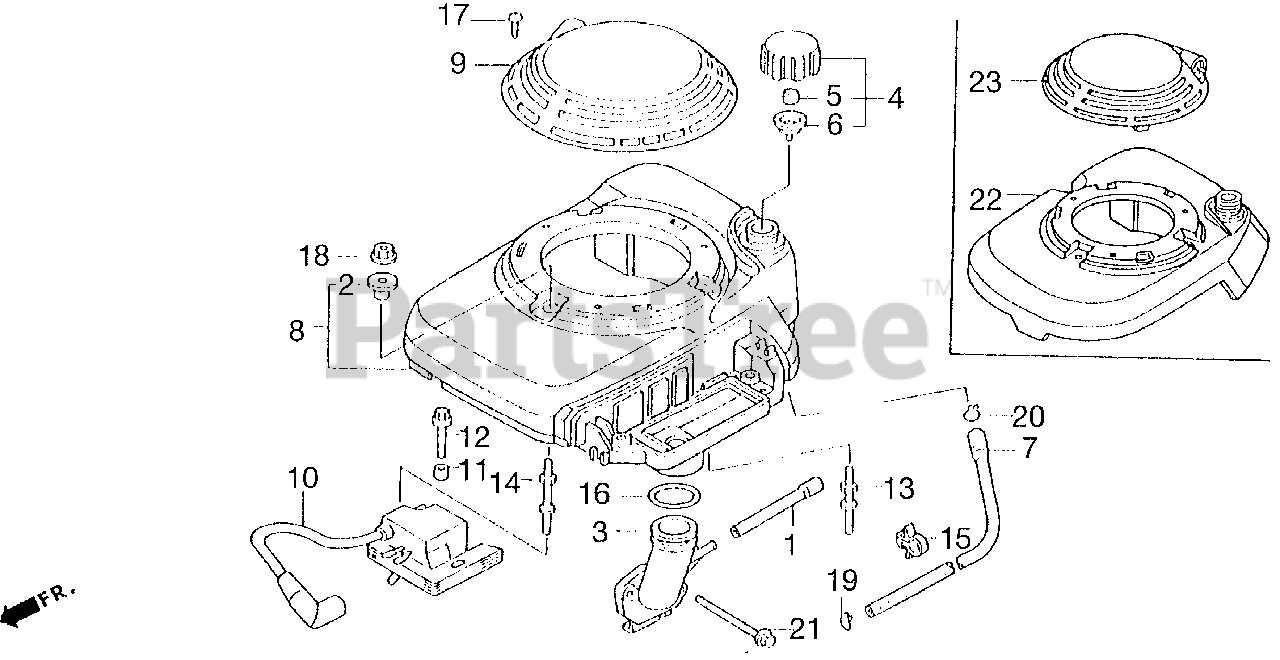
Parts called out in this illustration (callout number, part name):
1	TUBE, BREATHER
2	COLLAR, AIR CLEANER
3	ELBOW, AIR CLEANER
4	CAP ASSY., FUEL TANK
5	SPONGE, FUEL CAP BREATHER
6	GASKET, FUEL CAP
7	TUBE, FUEL TANK
8	COVER, FAN *R8* (TEXTURED) (BRIGHT RED)
8	COVER, FAN *R8* (BRIGHT RED)
9	HOOD, FAN COVER *R8* (TEXTURED) (BRIGHT RED)
10	COIL ASSY., IGNITION
11	COLLAR, ROTO-STOP
12	BOLT, FLANGE (6X32)
13	BOLT, STUD (BRAKE)
14	BOLT C, STUD
15	CLIP B, CABLE
16	O-RING (33.3X3.5)
17	SCREW, TAPPING (4X20)
18	NUT, FLANGE (6MM)
19	CLIP, TUBE (B8)
20	CLIP, TUBE (B10)
21	BOLT, FLANGE (6X100)
